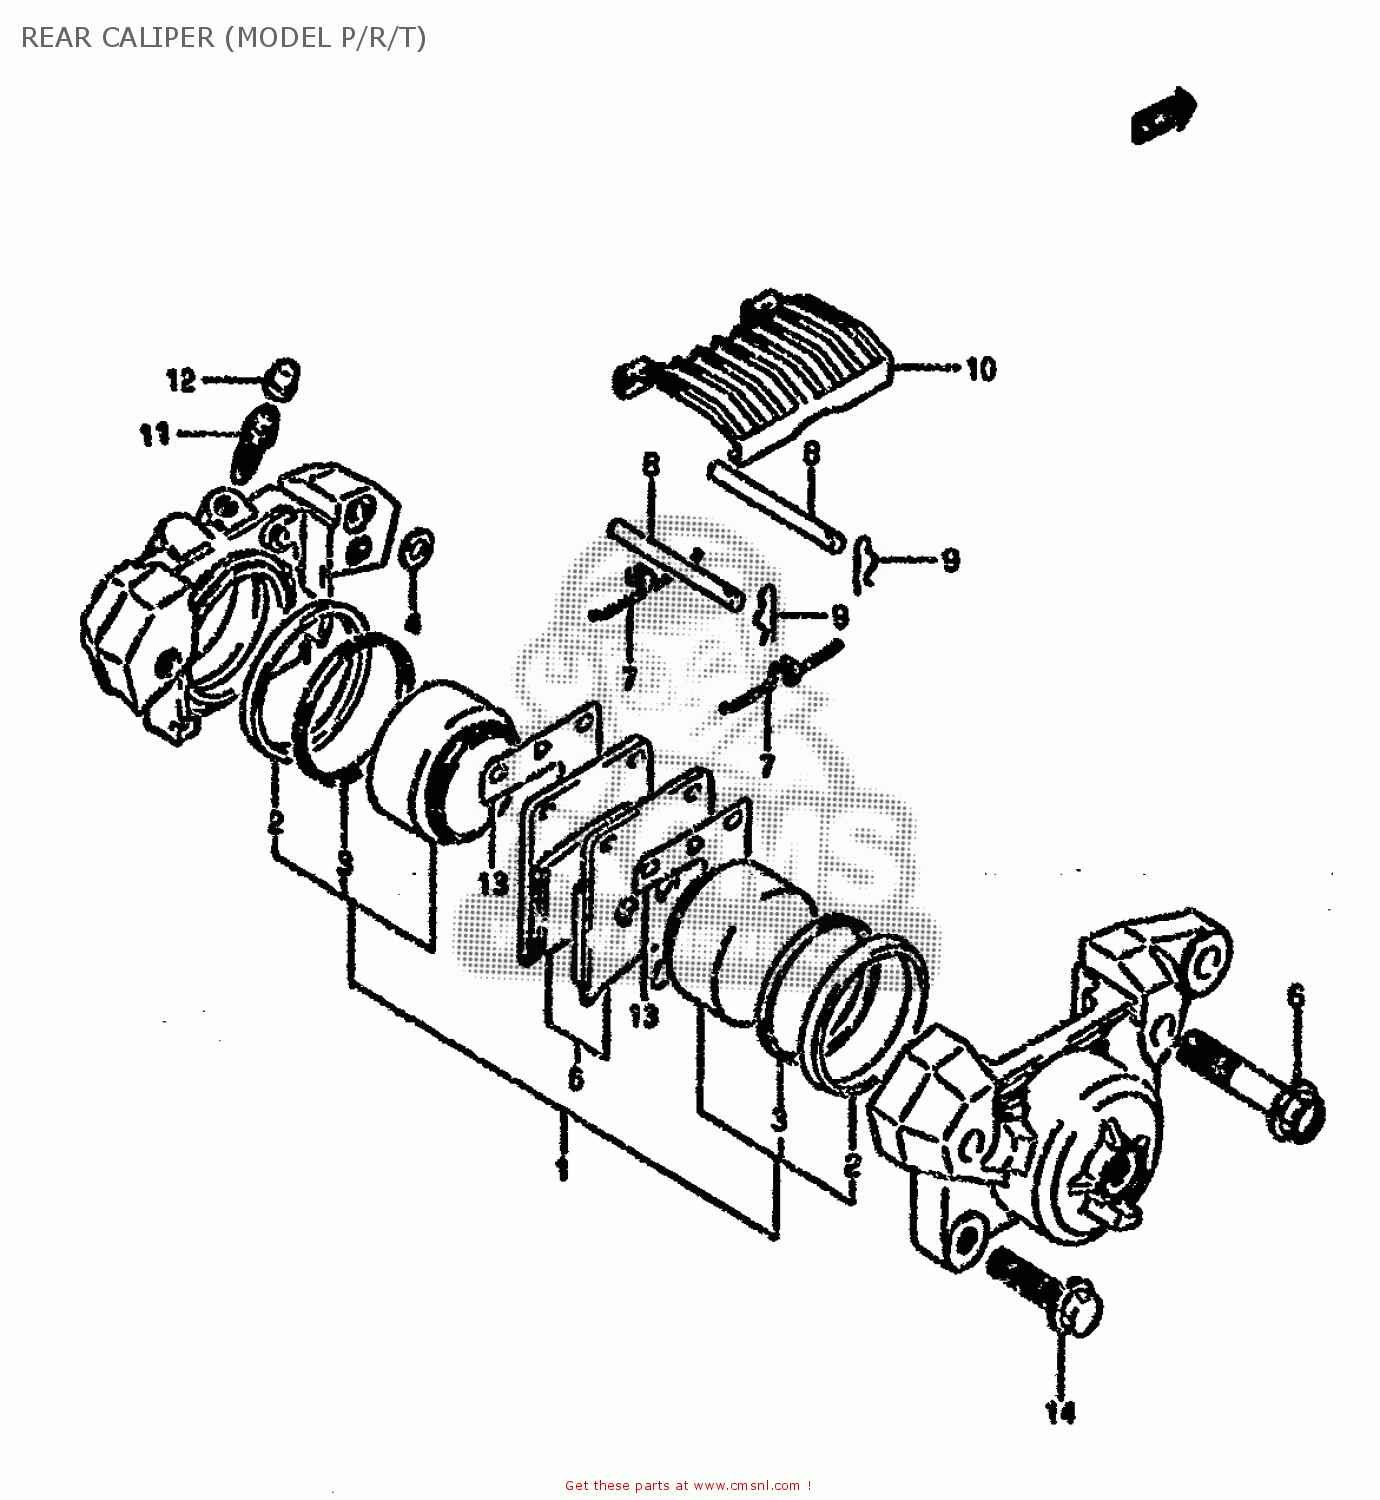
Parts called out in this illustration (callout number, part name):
1	PISTON SET
2	SEAL,FR CALIPE
3	SEAL,WIPER
4	SEAL,JOINT
5	PAD SET (NAS)
6	BOLT
7	SPRING
8	PIN,PAD
9	CLIP,PAD PIN
10	COVER
11	BLEEDER
12	CAP,BLEEDER PLUG
13	SHIM,RR CALIPER
14	BOLT
